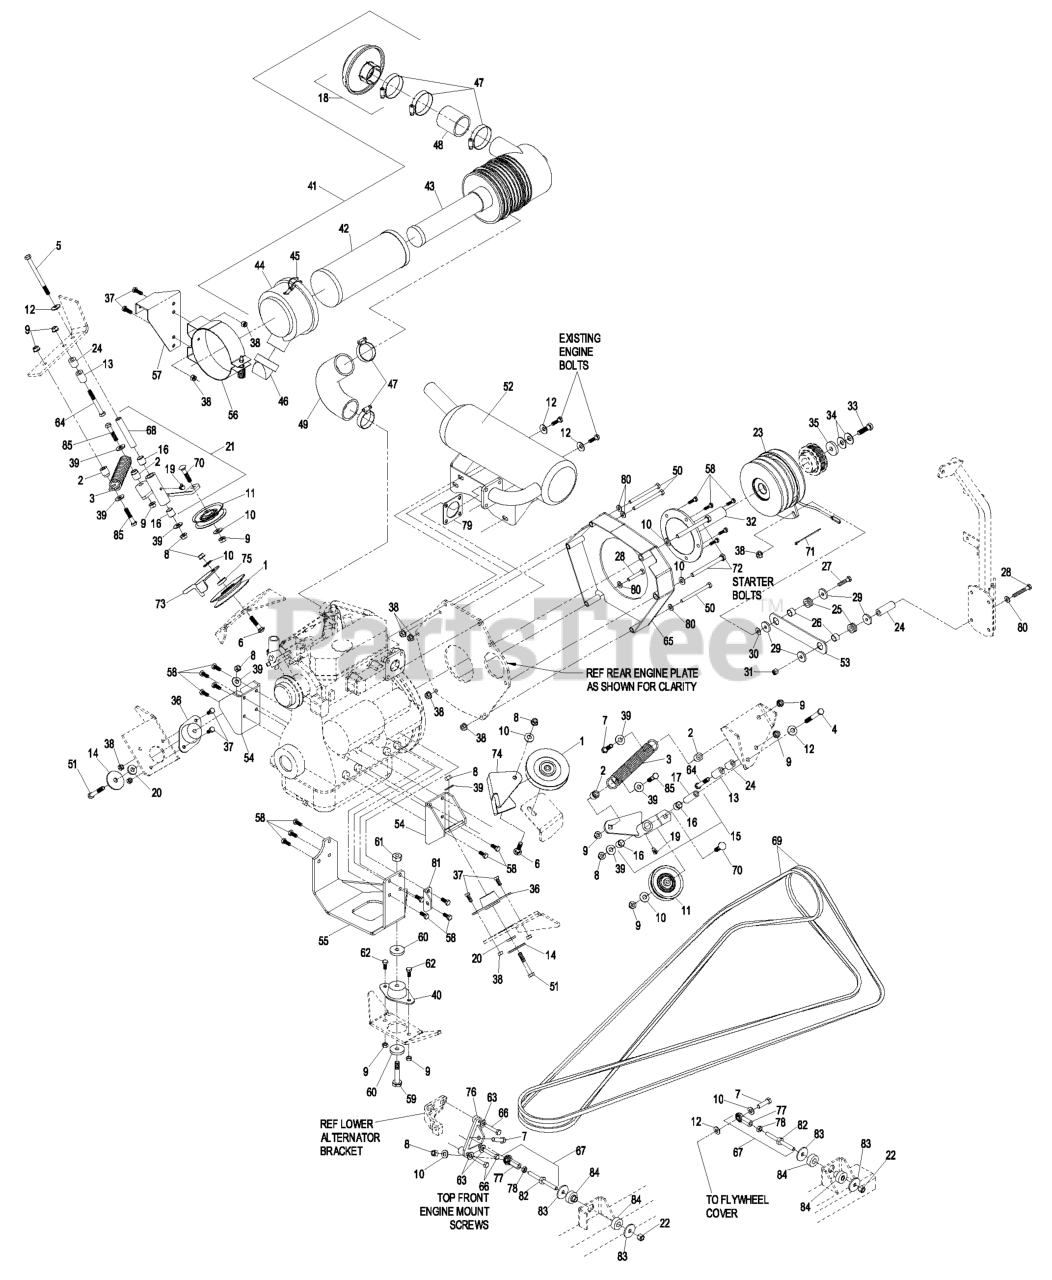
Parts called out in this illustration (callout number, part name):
2	SPACER-TIGHTENER, BELT
3	SPRING-EXTENSION
4	SCREW-HH
5	SCREW-HH
6	BOLT-CARR, SHORT NECK
7	SCREW-HH
8	NUT-LOCK, NI
9	NUT-HHF, WHIZ
10	WASHER-FLAT
12	WASHER-BELLEVILLE
13	SPACER-HYDRO CONTROL, LH
14	WASHER-FLAT
16	SLEEVE-BEARING
17	BUSHING-TIGHTENER, PIVOT
18	HOOD-CLEANER, 2" AIR INTA
19	FITTING-GREASE, 90 DEG
22	NUT-LOCK
24	SPACER-STRAP, CLUTCH
25	GROMMET
27	SCREW-HH
28	SCREW-HH
30	WASHER-FLAT
31	NUT-LOCK, NI
32	SHAFT-STUB
33	SCREW-HH
34	WASHER-SPRING
35	WASHER-CLUTCH
36	ISOLATOR-SIDE
37	SCREW-HH
39	WASHER-FLAT
40	ISOLATOR-REAR
41	FILTER-AIR
42	FILTER-AIR
43	FILTER-AIR, SAFETY
44	COVER-FILTER, AIR
45	LATCH-CLEANER, AIR
46	VALVE-VACUATOR
47	CLAMP-HOSE
48	HOSE-INTAKE
50	SCREW-HH
51	BOLT-CARR
52	MUFFLER KIT
53	STRAP-CLUTCH / BRAKE
54	LH AND RH ENGINE MOUNT AS
55	REAR ENGINE MOUNT ASM
56	BRACKET-FILTER, AIR
57	MOUNT-CLEANER, AIR
58	SCREW-HH
59	SCREW-HH
60	WASHER-THRUST
61	NUT-LOCK, NI
62	SCREW-HH
63	WASHER-SPRING
64	SCREW-HH
65	COVER-FLYWHEEL
66	SCREW-HH
67	BALL JOINT LINK ASM
68	BUSHING-TIGHTENER, PIVOT
69	BELT-V
70	SCREW-CARR
71	TIE-PLASTIC
72	SCREW-HH
73	GUARD-BELT SHEAVE, RH
74	GUARD-BELT SHEAVE, LH
75	SPACER-BRACKET, GUIDE
76	BRACKET-ENGINE, FRONT
77	JOINT-BALL, END
78	NUT-HJ
79	GASKET-MUFFLER
80	WASHER-PLAIN
81	BRACKET-GROUND
82	LINK,REAR A-T AXIAL
84	ISOLATOR-LINK
85	SCREW-HH
